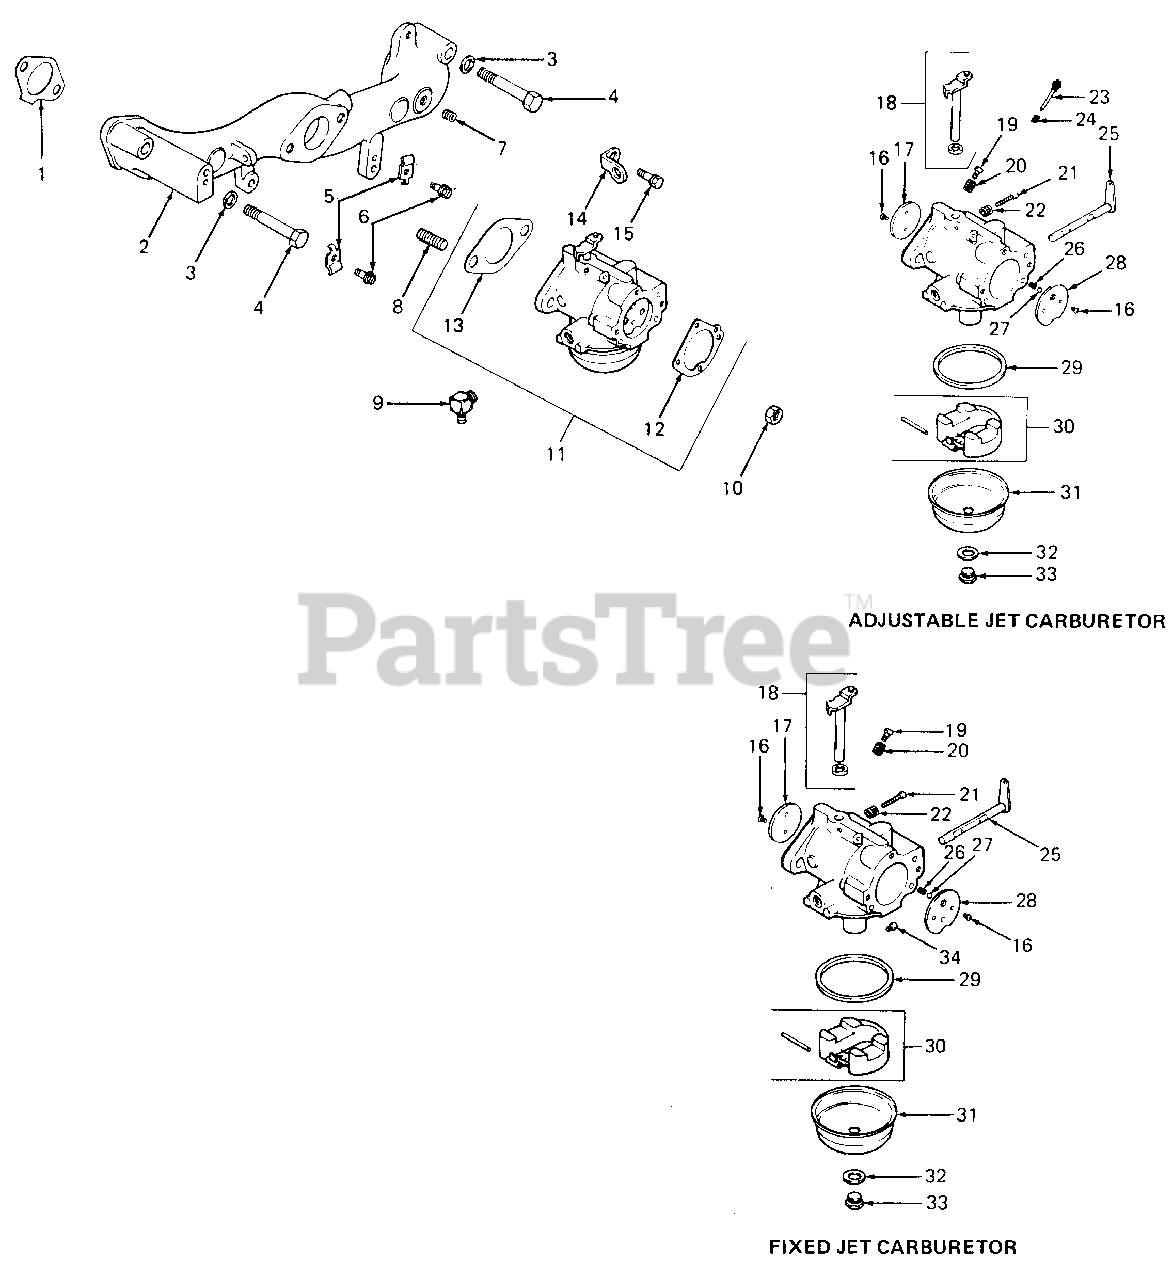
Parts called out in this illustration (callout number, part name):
1	Gasket, Manifold
2	Kit, Intake Manifold
3	Washer, Plain, 5/16
4	Screw, Hex Cap, 5/16-18 X 2.0 Lg
5	Clamp, Cable
6	Screw, Hex Wash Hd, #10-24 X 3/8 Lg
7	Plug, 1/8 NPTF
8	Stud, 5/16-18 X 1.0 Lg
9	Connector, 90
10	Nut, Hex, 5/16-18
11	Carburetor Assy w/Gasket
12	Gasket, Air Intake Elbow
13	Gasket, Carburetor
14	Strap, Lifting
15	Screw, Hex Wash, 1/4-20 X 5/8 Lg
16	Screw, Throttle & Choke Plate
17	Plate, Throttle
18	Shaft, Throttle w/Lever & Seal
19	Needle, Idle Fuel Adj
20	Spring, Idle Fuel
21	Screw, Idle Speed Adj
22	Spring, Idle Speed
23	Needle, Main Fuel
24	Spring, Main Fuel
25	Lever, Choke
26	Spring, Choke Friction
27	Ball, Choke Friction
28	Plate, Choke
29	Gasket, Bowl
32	Gasket, Bowl Retainer Screw
33	Screw, Bowl Retainer
